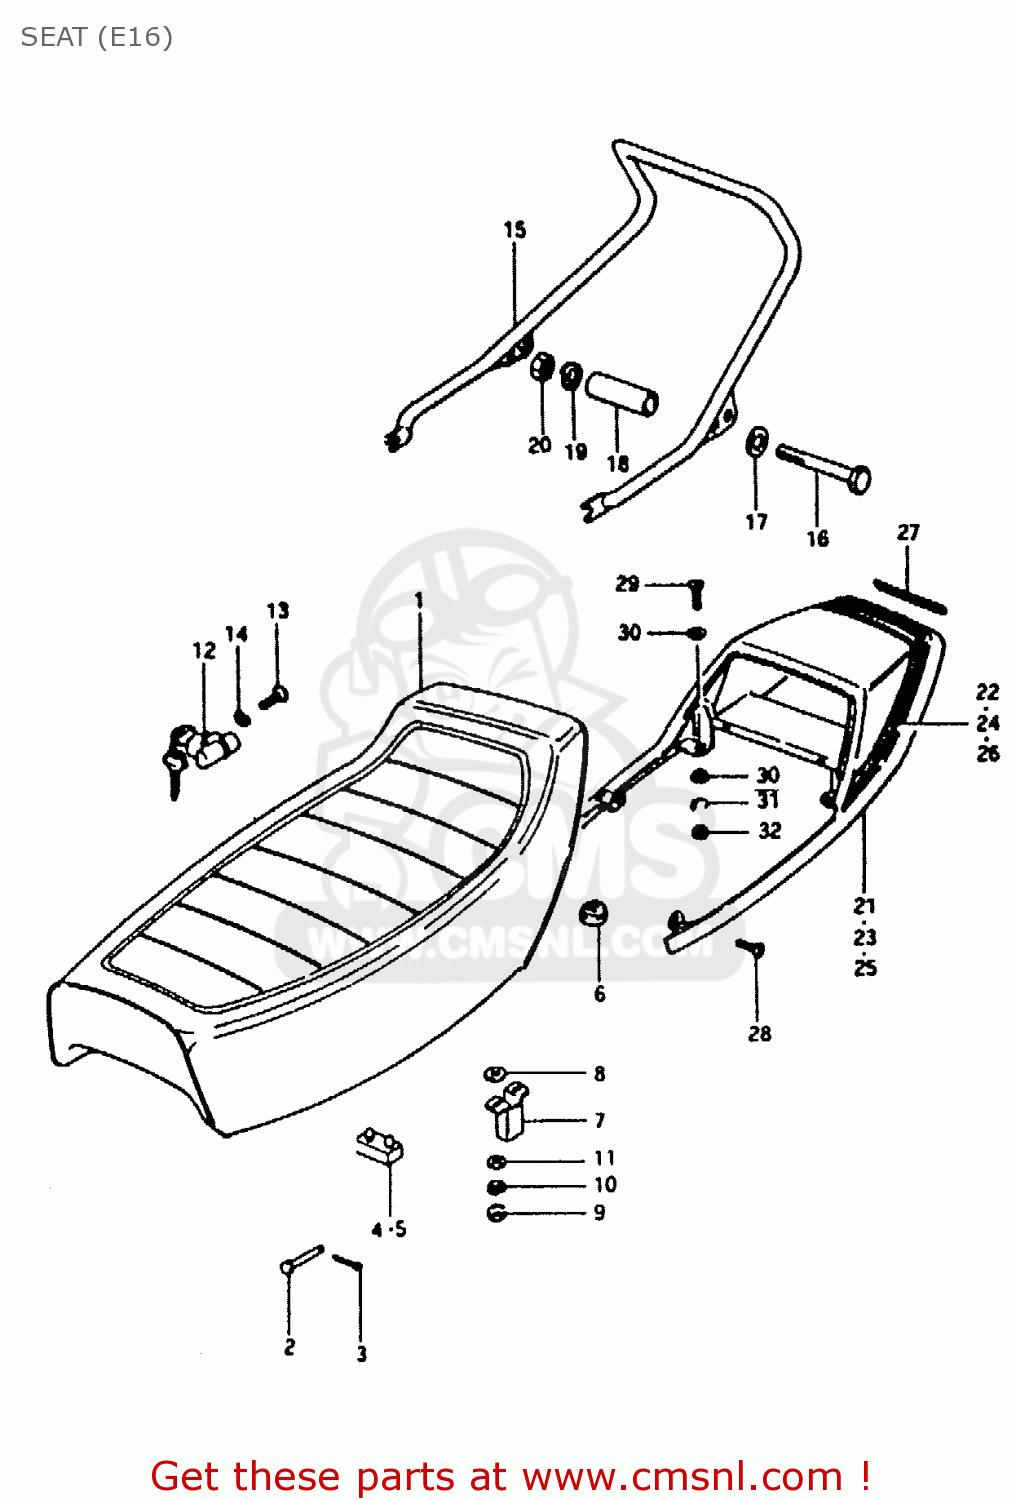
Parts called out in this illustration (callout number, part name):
1	SEAT ASSY
2	PIN
3	PIN
4	CUSHION
5	CUSHION
6	CUSHION
7	PLATE,CLAMP GUIDE
8	WASHER(6.5X18X1)
9	NUT
10	LOCK WASHER
11	WASHER
12	LOCK ASSY,SEAT
13	SCREW
14	LOCK WASHER
15	BAR, PILLION RIDER
16	BOLT 10X65
17	WASHER
18	SPACER
19	LOCK WASHER
20	NUT
21	COVER, SEAT TAIL
22	TAPE SET
23	COVER, SEAT TAIL
24	TAPE SET
25	COVER, SEAT TAIL
26	TAPE SET
27	EMBLEM,SEAT TAIL COVER RR
28	SCREW
29	SCREW
30	WASHER
31	LOCK WASHER
32	NUT 6MM
